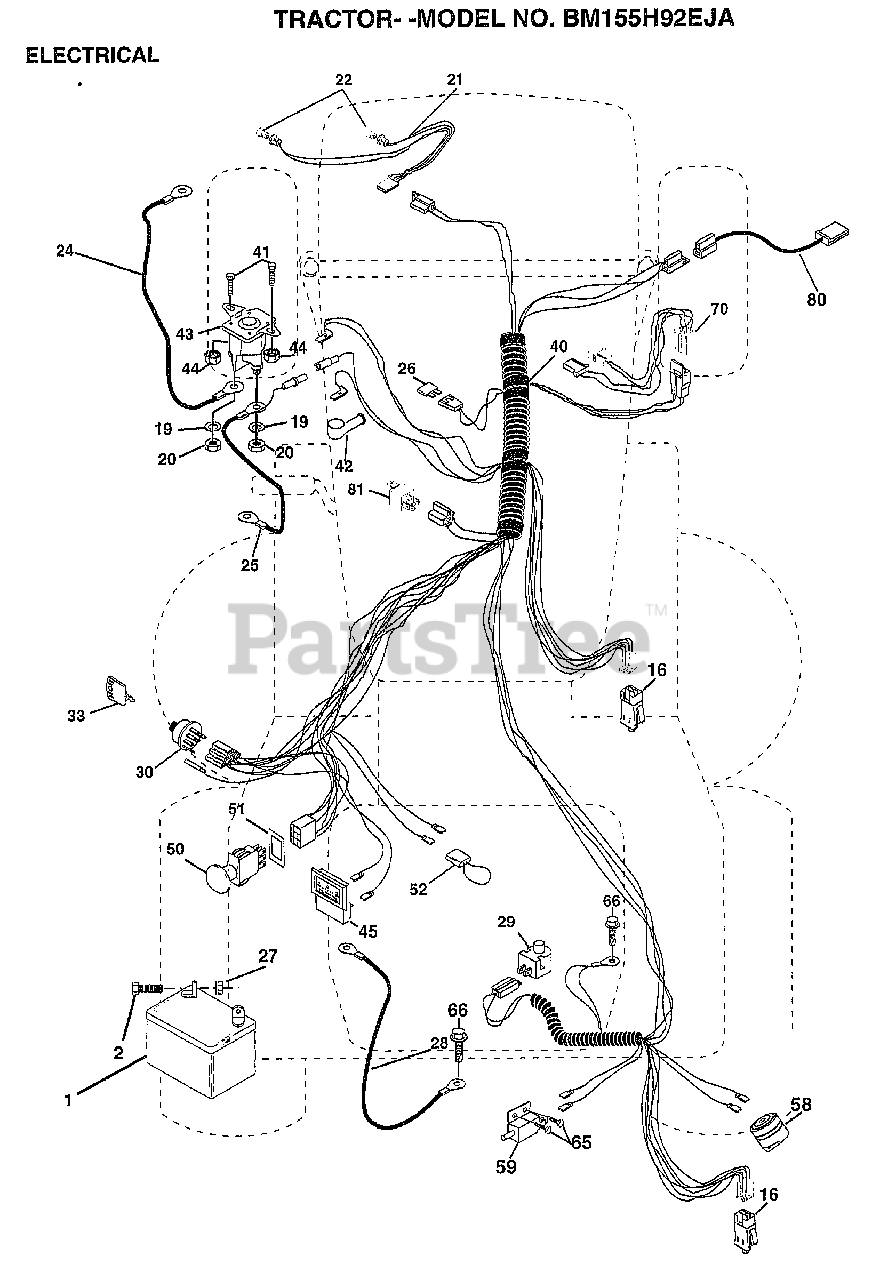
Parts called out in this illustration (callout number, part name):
2	BOLT LT
16	SWITCH INTERLOCK
20	NUT
21	HARNESS.ASM.LIGHT W/4152J
22	HEADLAMP BULB
24	"CABLE T, BATTERY"
25	CABLE.BATTERY.CRD
26	FUSE.15 AMP
27	NUT
28	"CABLE.GRD.6GA/18""BLACK"
29	SWITCH.PLUNGER
30	SWITCH IGN 4POS
31	NUT IGNITION
32	COVER KEY SWITCH
33	KEY
40	HARNESS.IGN.CRD.ELECT
41	BOLT HXHD FIN
44	NUT HXKEP 1/4X20
45	AMMETER
50	PTO SWITCH.BLK
51	RING RETAIN PTO
52	PROTECTION LOOP
59	SWITCH.FBI.CRD
65	SCREW
66	SCREW LT
70	HARNESS.ENGINE
80	HARNESS.CLUT.EVX.
81	RELAY ASSY T
